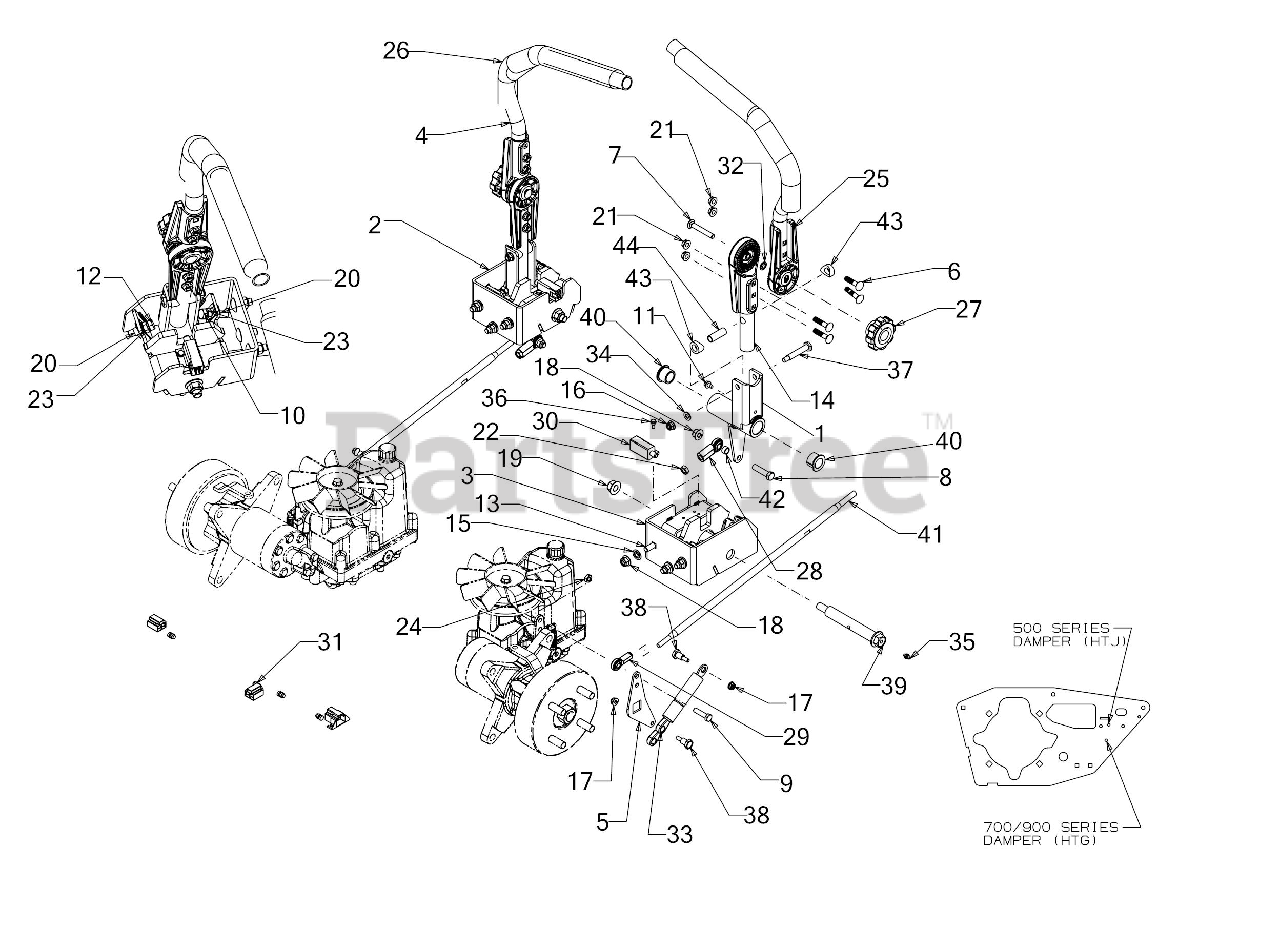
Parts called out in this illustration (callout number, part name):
1	LAPBAR PIVOT CONTROL ASSEMBLY
2	LAPBAR PIVOT HOUSING (LH)
3	LAPBAR PIVOT HOUSING (RH)
4	LAPBAR HANDLE TUBE ASSEMBLY
5	DAMPER BRACKET
6	CARRIAGE BOLT 5/16-18 x 1.50
7	SCRE W5/16-18 x 2.25 GR5
8	SCREW 3/8-16 x 1.50
9	SCREW 5/16-18 x 1.25 GR5
10	SCREW 3/8-16 x 1.50 GR8
11	SCREW 1/4-20 x .375
12	SCREW 3/8-16 x 1.25 GR5
13	CARRIAGE BOLT 3/8-16 x 1.00 GR5
16	FLANGE LOCK NUT 5/16-18
17	FLANGE LOCK NUT
20	U NUT 3/8-16
21	FLANGE NUT
22	HEX JAM NUT 3/8X24
24	HEX NUT TOP LOCK 5/16-18 GR 8
25	HANDLE ADJUST
27	KNOB-5/16-18
28	BALL JOINT (RH)
29	END ROD- 5/16 (LH)
30	INTERLOCK SWITCH (NO/NC)
31	ADAPTER HARNESS - LAPBAR
33	DAMPNER CYLINDER
34	FLAT WASHER
35	GREASE ZERT 1/4-28
36	SHOULDER SCREW
37	SHOULDER SCREW
38	SHOULDER BOLT .395 DIA x .56 LG
39	SHOULDER BOLT 1.0 X 4.75 1/2-13
40	FLANGE BEARING
43	NYLON SPACER
